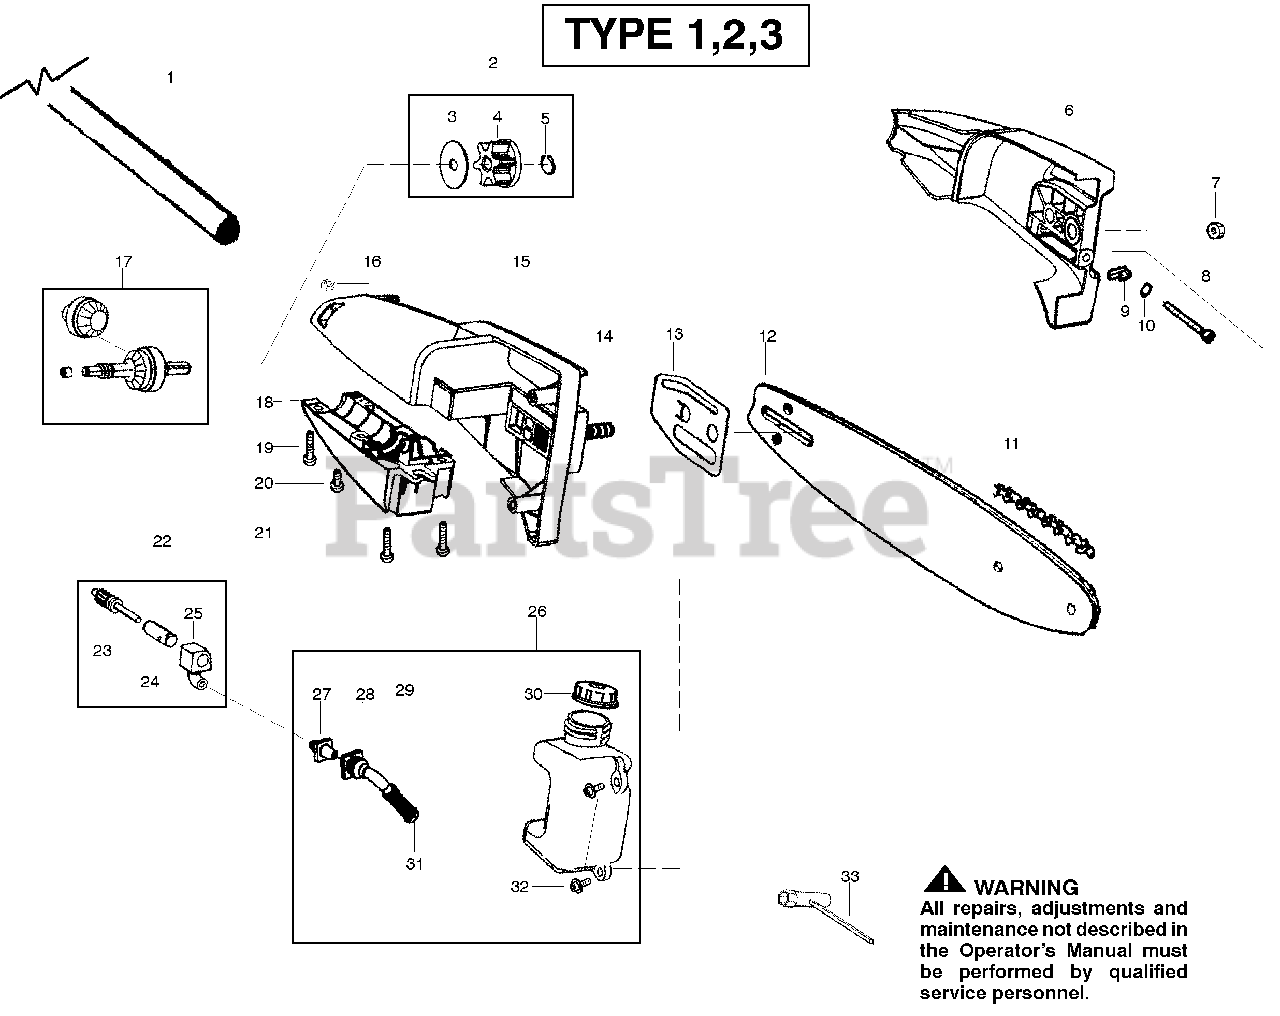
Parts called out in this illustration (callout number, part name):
1	Assy-Driveshaft
2	Kit-Sprocket Assy.
4	Sprocket
5	Retainer-Sprocket
6	Assy-Bar Clamp
7	Nut-Bar Mounting
8	Kit-Bar Adjust
9	Pin-Bar Adjust
10	Retainer-Bar Adjust
11	Accy.-Chain-8"
13	Plate-Bar pad
14	Bolt-Bar
15	Hsg.-Upper
17	Kit-Gear Assy
18	Hsg.-Lower
20	Screw-Align
22	Kit-Oil Assy
23	Assy-Gear Plunger
25	Block-Oil
26	Assy-Oil Tank
27	Fitting-Oil Line
28	Intake-Oil Line
29	Filter-Oil
30	Cap-Oil
31	Plug-Oil Filter
33	Wrench-Bar
